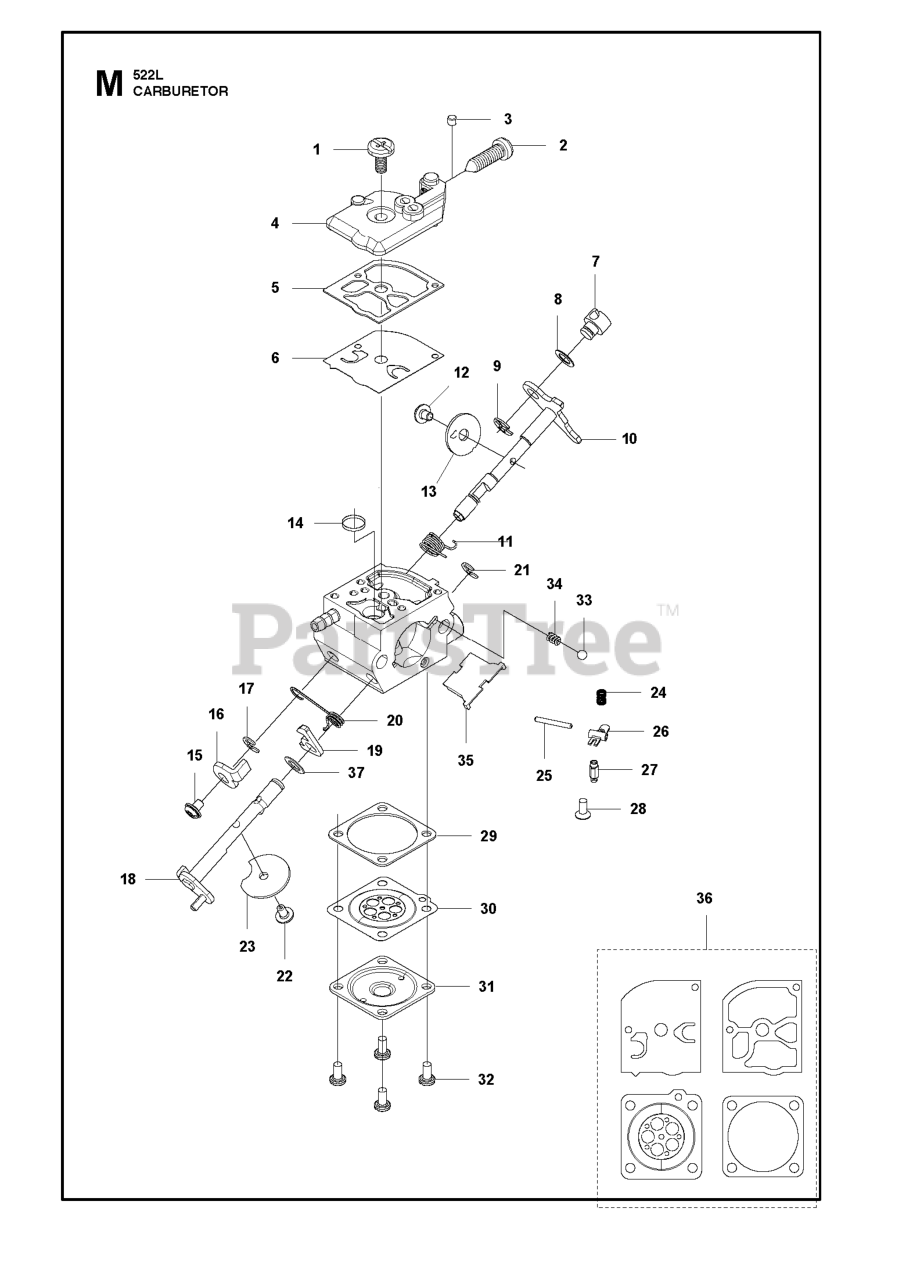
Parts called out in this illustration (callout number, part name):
4	PUMP COVER
5	GASKET PUMP
6	DIAPHRAGM PUMP
10	SHAFT ASSY, THROTTLE
11	SPRING
13	VALVE THROTTLE
16	LEVER THROTTLE OUTER
18	SHAFT ASSY, CHOKE
23	VALVE CHOKE T0.8
27	VALVE INLET
28	SCREW M3X6
29	GASKET METERING CHAMBER
30	DIAPHRAGM ASSY METERING
31	COVER METERING CHAMBER
32	SCREW M3X7
33	BALL STEEL
34	SPRING FRICTION
36	GASKET KIT
